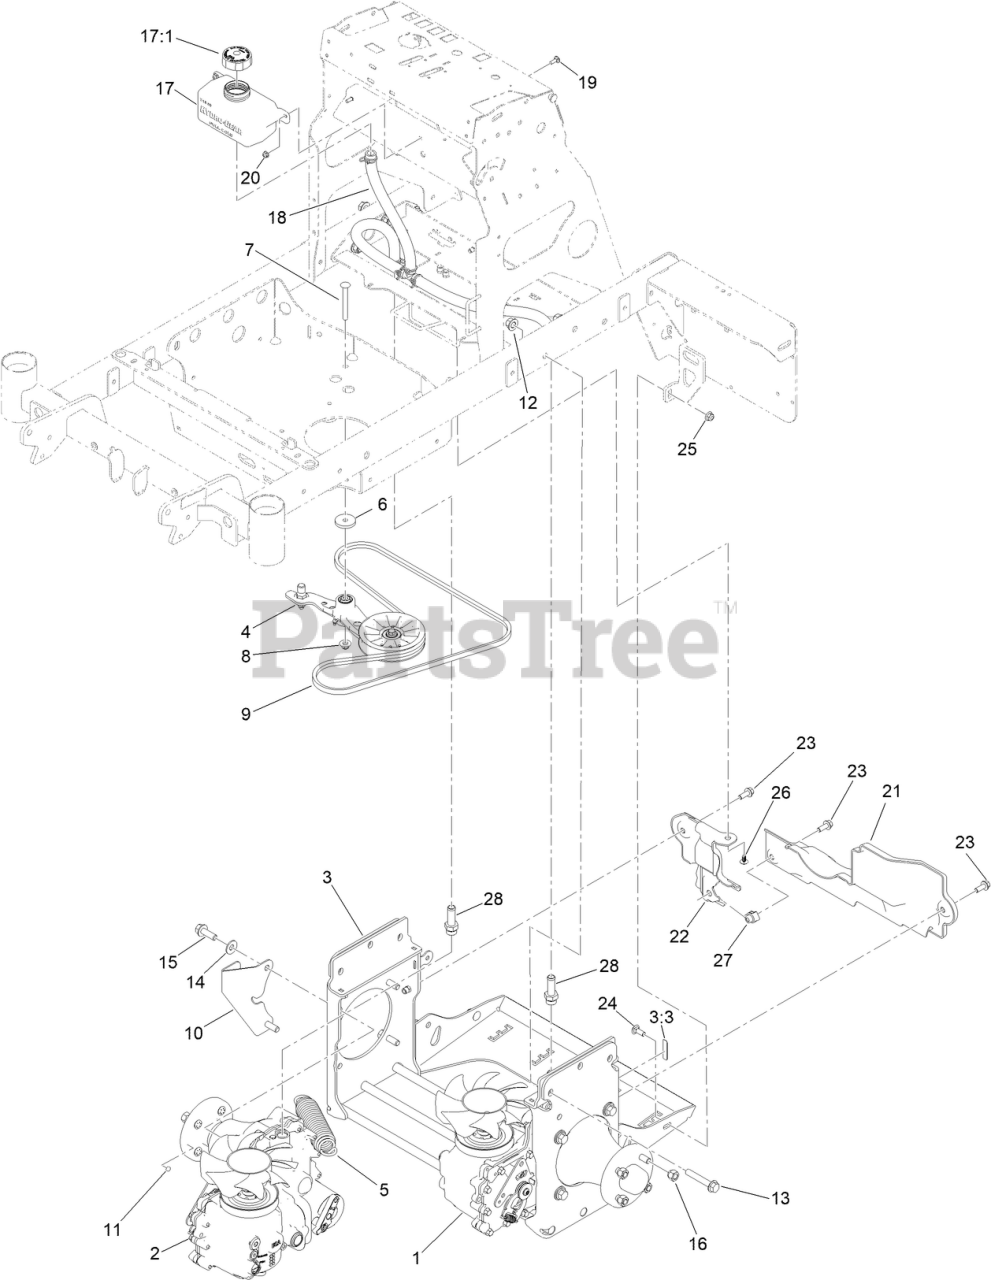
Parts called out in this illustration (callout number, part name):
1	ZT5400-LEFT
2	ZT5400-RIGHT
3	FRAME-ASM, ZT5400
3:3	DECAL-WARNING
4	ASM-PUMP IDLER
5	SPRING-EXTENSION
6	WASHER-PLAIN
7	BOLT-SHOULDER, CARRIAGE 3/8-16 X 3 1/2
8	Nut-Nyloc 3/8-16 Flg
9	BELT-V, COGGED
10	BRACKET-SENSOR, SPEED
11	MAGNET, SPEEDOMETER
12	Nut-Lock 1/2-13
13	SCREW-HF
14	WASHER-SPRING
15	SCREW-HHF
16	NUT-LUG
17	HYDRAULIC RESERVOIR ASM
17:1	CAP-RESERVOIR, HYD
18	ASM-HOSE, EXPANSION
19	BOLT,CARRIAGE,1/4-20X3/4,ST/ST
20	Nut-Hex Flange
21	COVER-REAR, LT
22	COVER-REAR, RT
23	SCREW-HHF
24	SCREW-CARR
25	Nut-Hex Flange
26	PLUG-PLASTIC
27	NUT-TINNERMAN
28	FITTING-STRAIGHT, 5/8 HOSE BARB
